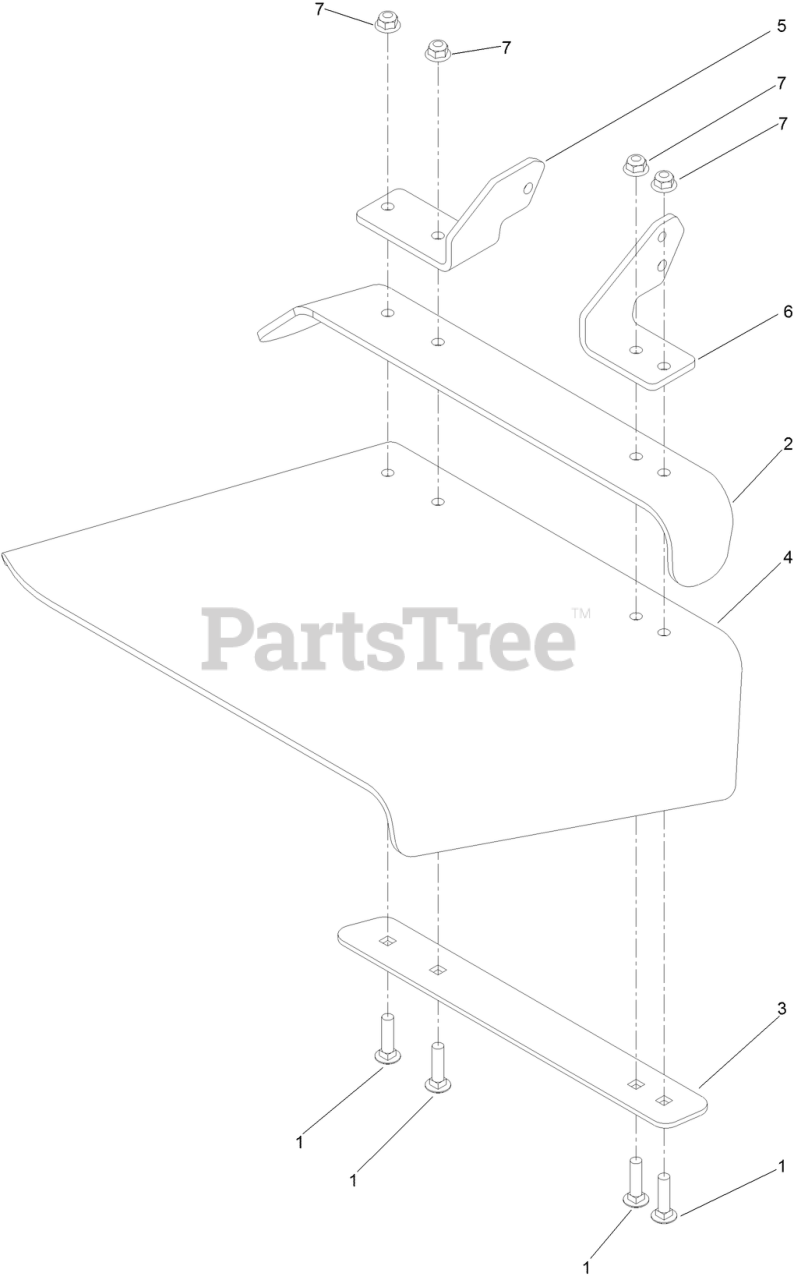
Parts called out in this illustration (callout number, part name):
1	SCREW-CARR
2	DEFLECTOR
3	STRAP-DISCHARGE
4	DEFLECTOR-DECK, RUBBER
5	PLATE-HINGE, REAR
6	PLATE-HINGE, FRONT
7	NUT-HF, NI
